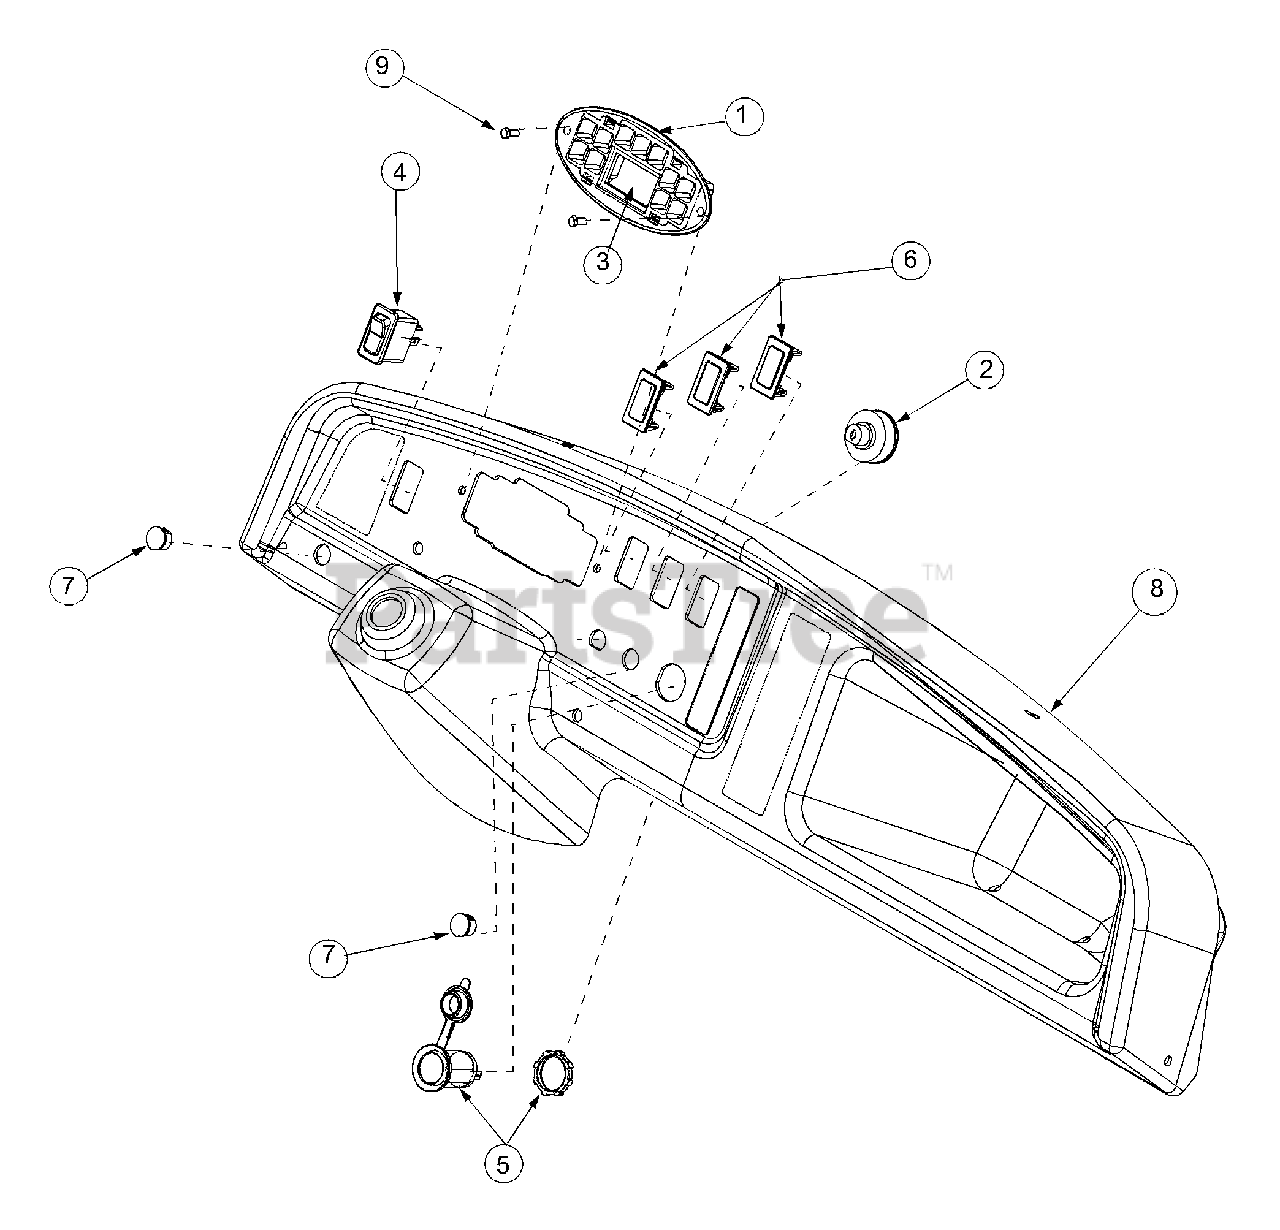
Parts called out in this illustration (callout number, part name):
1	Instrument Panel
2	Switch, Key
3	Meter, Hour
4	Rocker Switch, Headlight
5	Receptacle, Power, 12v
7	Plug, Horn Switch
8	Dash Panel
9	Nut, Retainer 1/8
